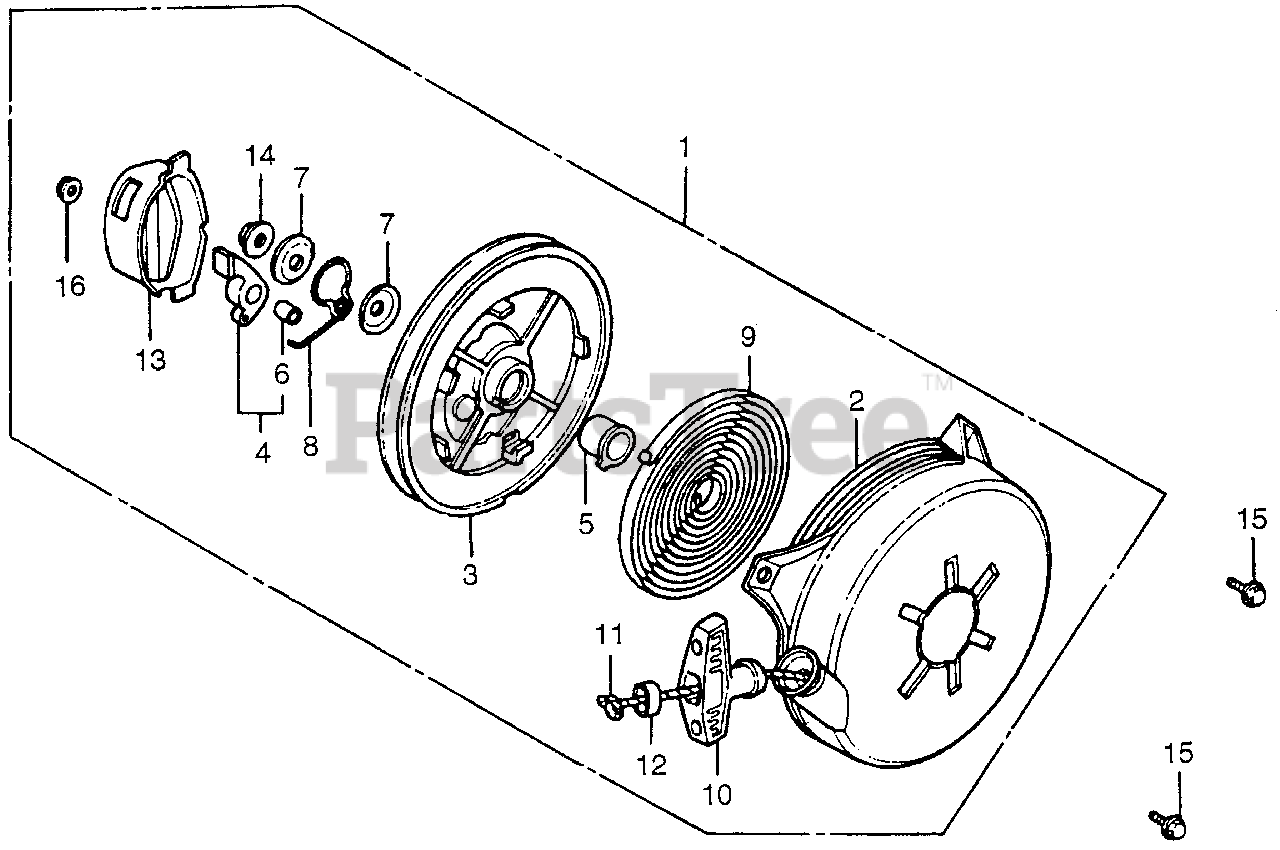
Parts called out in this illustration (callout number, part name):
1	STARTER ASSY., RECOIL *R8* (BRIGHT RED)
2	CASE, STARTER *R8* (BRIGHT RED)
3	REEL, STARTER
4	RATCHET KIT
5	BOSS, REEL
6	BUSH, RATCHET
7	PLATE, FRICTION
8	RATCHET KIT
9	SPRING, RETURN
10	GRIP, STARTER
11	ROPE, STARTER (#5X55")
12	SUPPORT, GRIP
13	COVER, REEL STARTER
14	NUT, SELF-LOCK (8MM)
15	BOLT-WASHER (6X10)
16	NUT, FLANGE (5MM)
